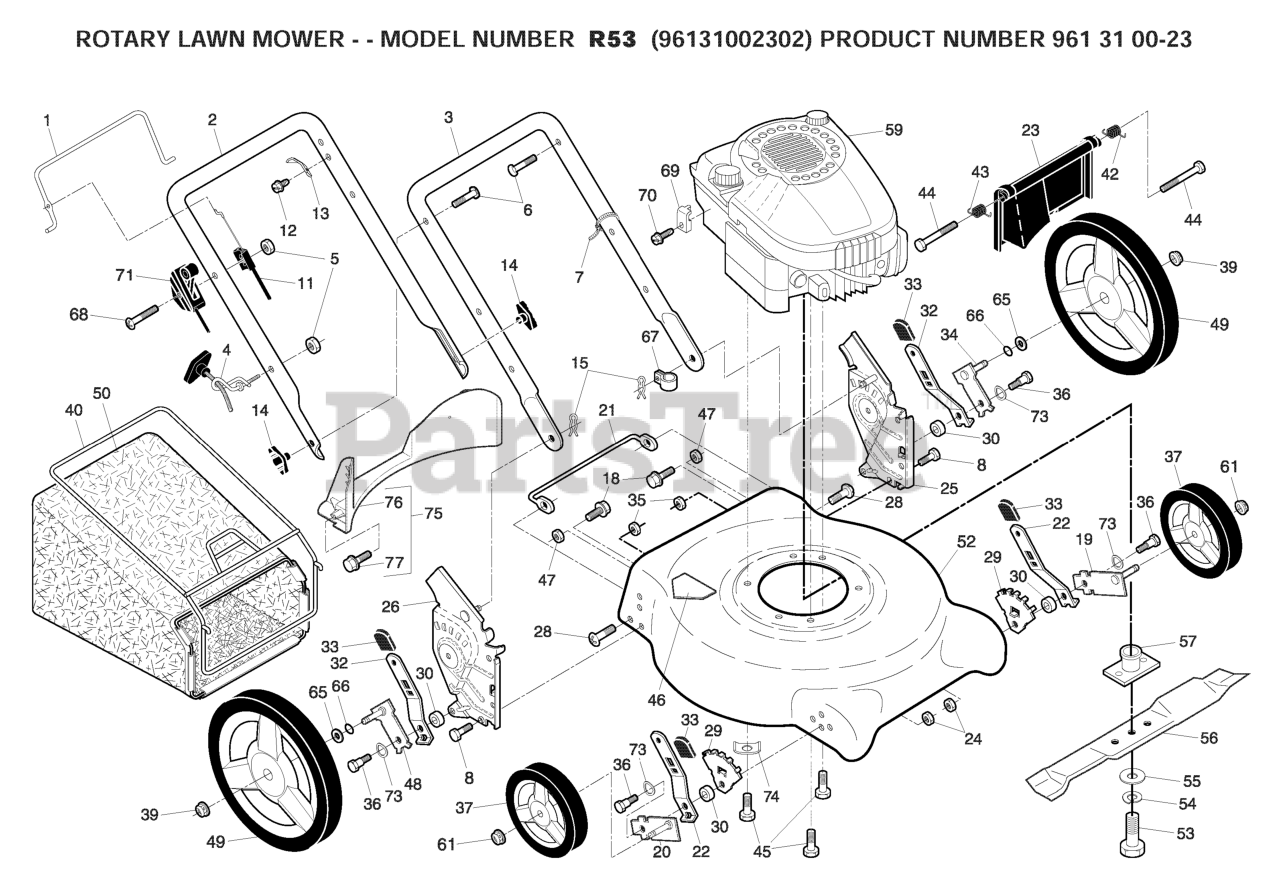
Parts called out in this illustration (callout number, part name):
1	BAIL.MZR.STD.BLACK
2	Upper Handle
3	HANDLE.LOWER.GREY
4	RB GUIDE.ROPE.STD.BLK.ZIN WSL
5	NUT
6	BOLT, HANDLE 5/16-18X1.75
7	TIE GUIDE
8	BOLT.FIN.HEX.5/16-18X3/4
11	ENGINE ZONE CONTROL
13	BRACKET UPSTOP
14	KNOB, DEFLECTOR
15	HAIRPIN COTTER
18	SCREW 1/4X20
19	AXLE ARM ASSY FRONT LH
20	AXLE ARM ASSY FRONT RH
22	SELECTOR SPRING, FRONT
23	REAR DOOR ASSY
24	LOCKNUT 5/16-18
25	RP BRKT.ASM.HAND.HW.21.LT.ORNG
26	RP BRKT.ASM.HAND.HW.21RT.ORNG
29	WHEEL ADJ BRACKET FRONT
30	SPACER.HEIGHT.ADJUSTER
32	SPRING.SEL.EXT.21.DOMED.12/14
34	AXLE ARM ASSY REAR LH
35	LOCKNUT 5/16-18
36	SHOULDER BOLT 5/16-18
37	WHEEL AND TIRE ASSY, REAR
39	NUT.HEX.FLANGE.3/8-16.LOCKNUT
40	FRAME.BAG.21.REAR.DOMED.PUSH
42	SPRING.LH.22.REAR.DOOR.EZ.EMPT
43	SPRING.RH.22.REAR.DOOR.EZ.
45	BOLT 3/8-16X1-1/8
46	DECAL.INTERNATIONL.CUTFINGER
48	AXLE ARM ASSY REAR RH
49	RP.WHEEL.12X1.75H 3 SPOKE.RAD
52	KIT.HSG.21.PUSH.ORANGE.CE
53	SCREW, HEX HD 3/8-24 X 1-3/8
54	LOCKWASHER
55	WASHER,HARDEN
56	BLADE.21.PUSH
57	ADAPTER.BLADE
61	NUT.HEX.FLANGE.3/8-16.LO(3 2)
65	WASHER.FLAT.1/2
66	O-RING..070X.487.NEOPRENE
67	CLIP.CABLE.BLK
69	CABLE CLAMP(ENGINE)
70	SCREW.HEX.HEAD.WASHER.10-16
71	THROTTLE CONTROL
73	WASHER.CURVED.CYLINDRICAL
74	WASHER.ENGINE.BZP
75	KIT.BAFFLE.REAR.PLASTIC.21.RD
76	BAFFLE.REAR.PLASTIC.21.RD.ECON
77	SCREW.HX.13X.750
